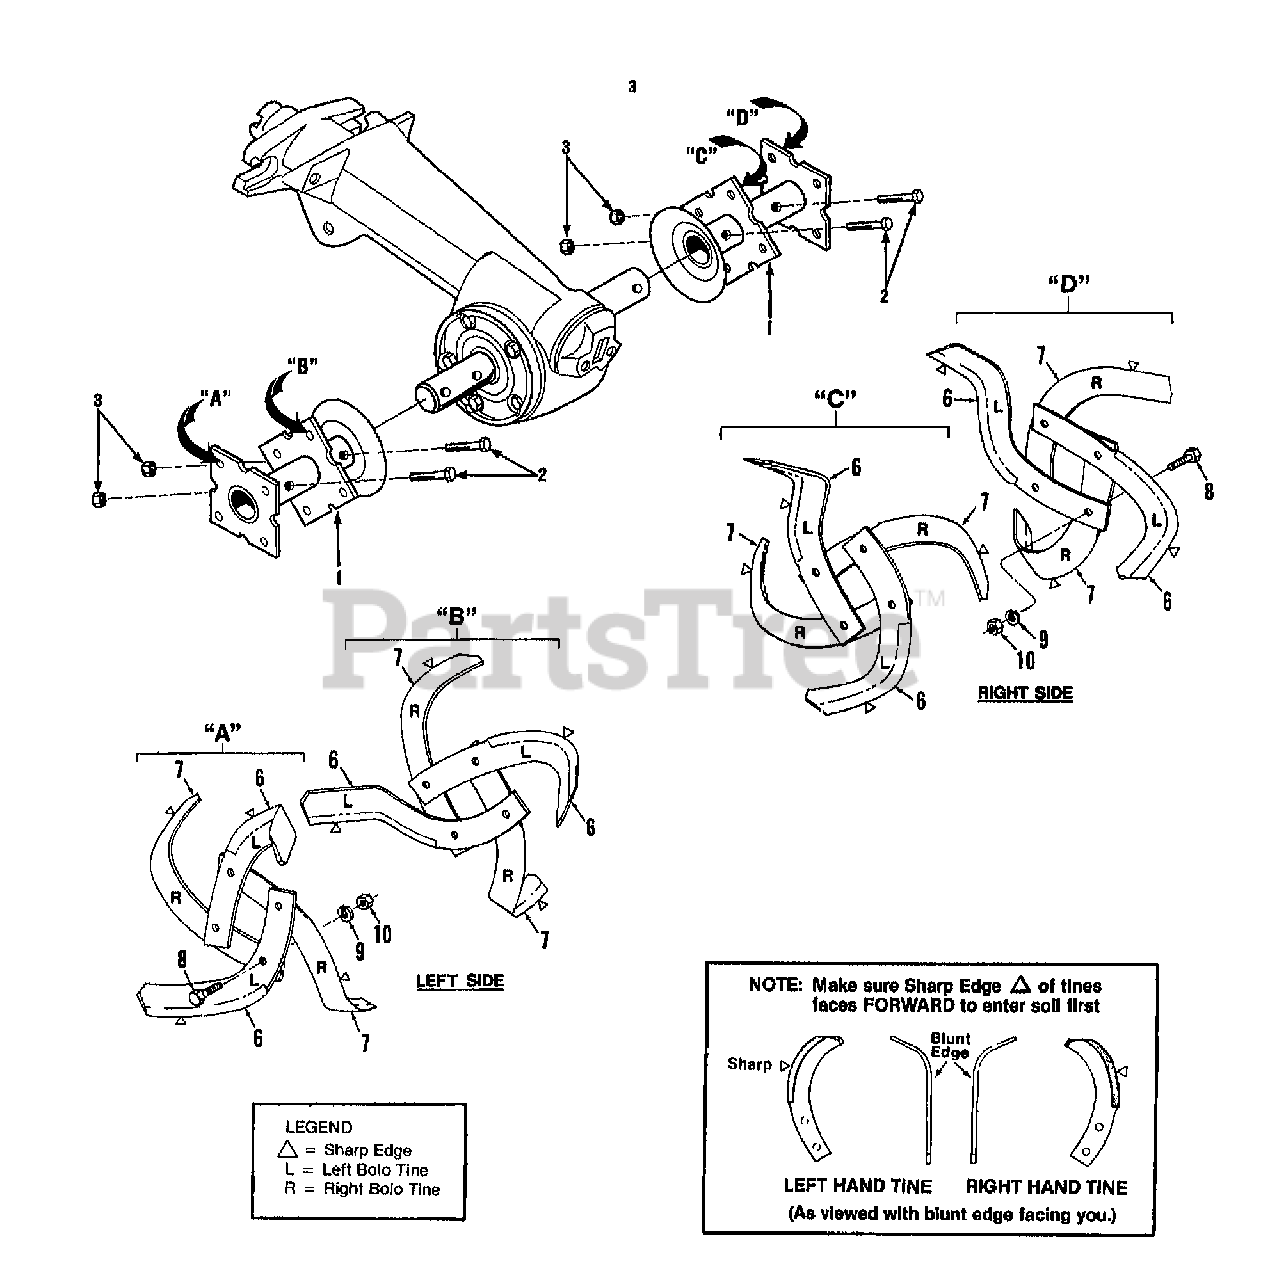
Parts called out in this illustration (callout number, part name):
1	HOLDER-TINE HORSE (RED)
2	SCR-HH 3/8-16X2.00 G8
3	NUT-H/LK 3/8-16
4	THIS REF. NO. NOT USED
5	THIS REF. NO. NOT USED
6	TINE-BOLO LT W/HDW(INCL. TWO EACH OF REF. NO.'S 8,9 AND 10)
7	TINE-BOLO RT W/HDW(INCL. SAME HARDWARE AS REF. NO.6)
8	SCR-HH 3/8-16X1.0 G5 ZP
9	WASHER-LK .375 @ DEPL
10	NUT-HEX 3/8-16 ZP
